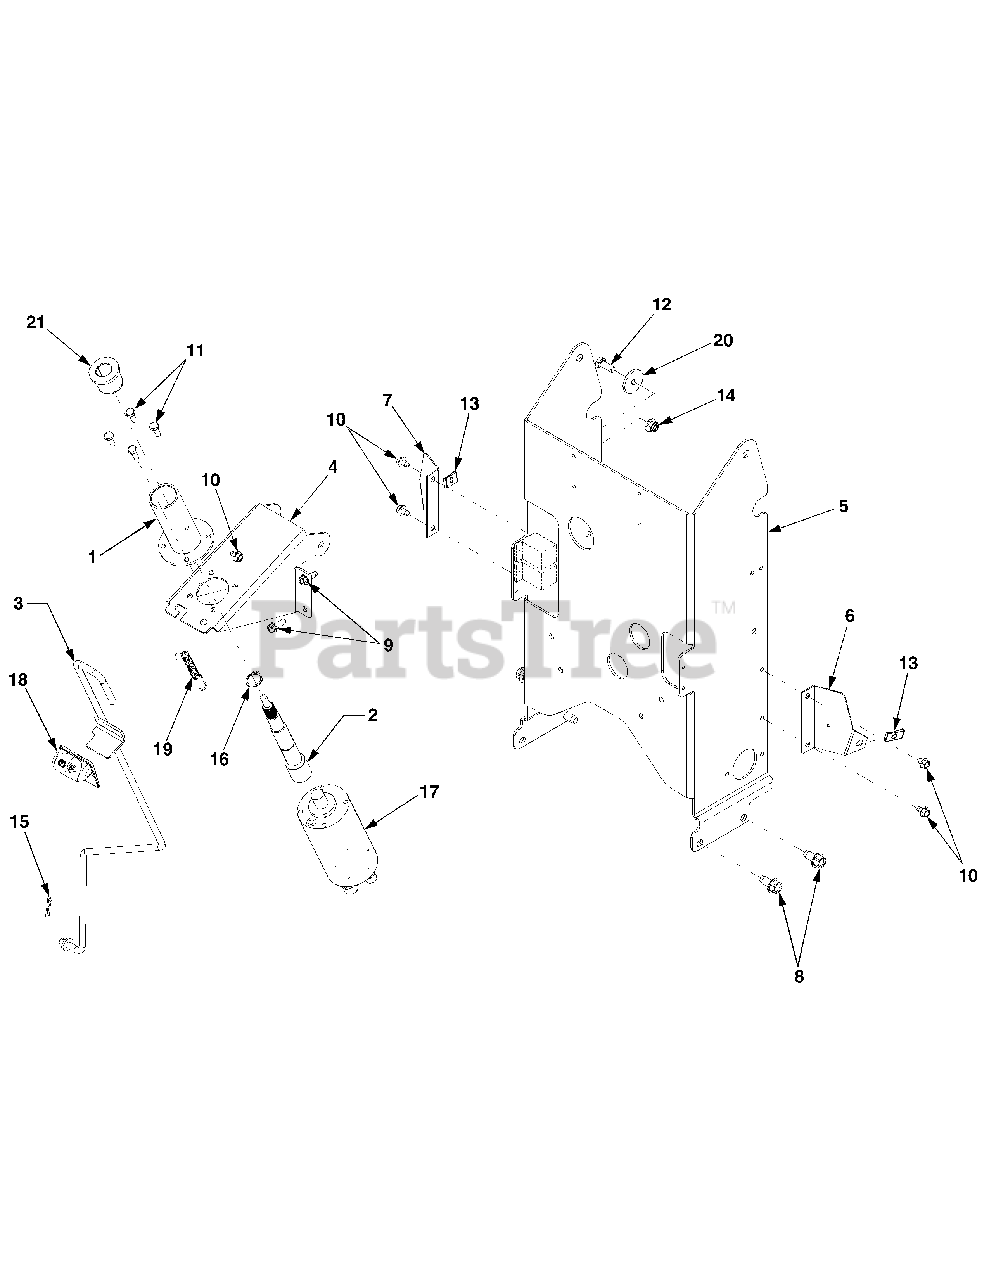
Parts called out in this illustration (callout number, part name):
3	Rod, Parking Brake
6	Bracket, Dash Mtg
7	Bracket, Dash Mtg
8	Screw, Hex Wash, Hd Tapp 3/8-16 x .75
9	Screw, Hex Wash, Hd Tapp 1/4-20 x .75
10	Screw, Hex Wash, Hd Tapp 1/4-20 x .375
11	Screw, Hex, M6-1 x 16 Hardened
12	Screw, Hex Cap 5/16-18 x .75 GR5
13	Nut, Speed, 1/4-20
14	Nut, Hex Insert Flange Lock, 5/16-18 GrF
15	Pin, Internal Cotter
16	Ring, Snap, .75 Dia
17	Pump, Hydraulic Steering
18	Lever, Parking Brake
19	Spring, Extension
20	Washer, Flat, .33 x 1.25 x .12
21	Bearing, Flg, .75 ID x 1.25 OD
